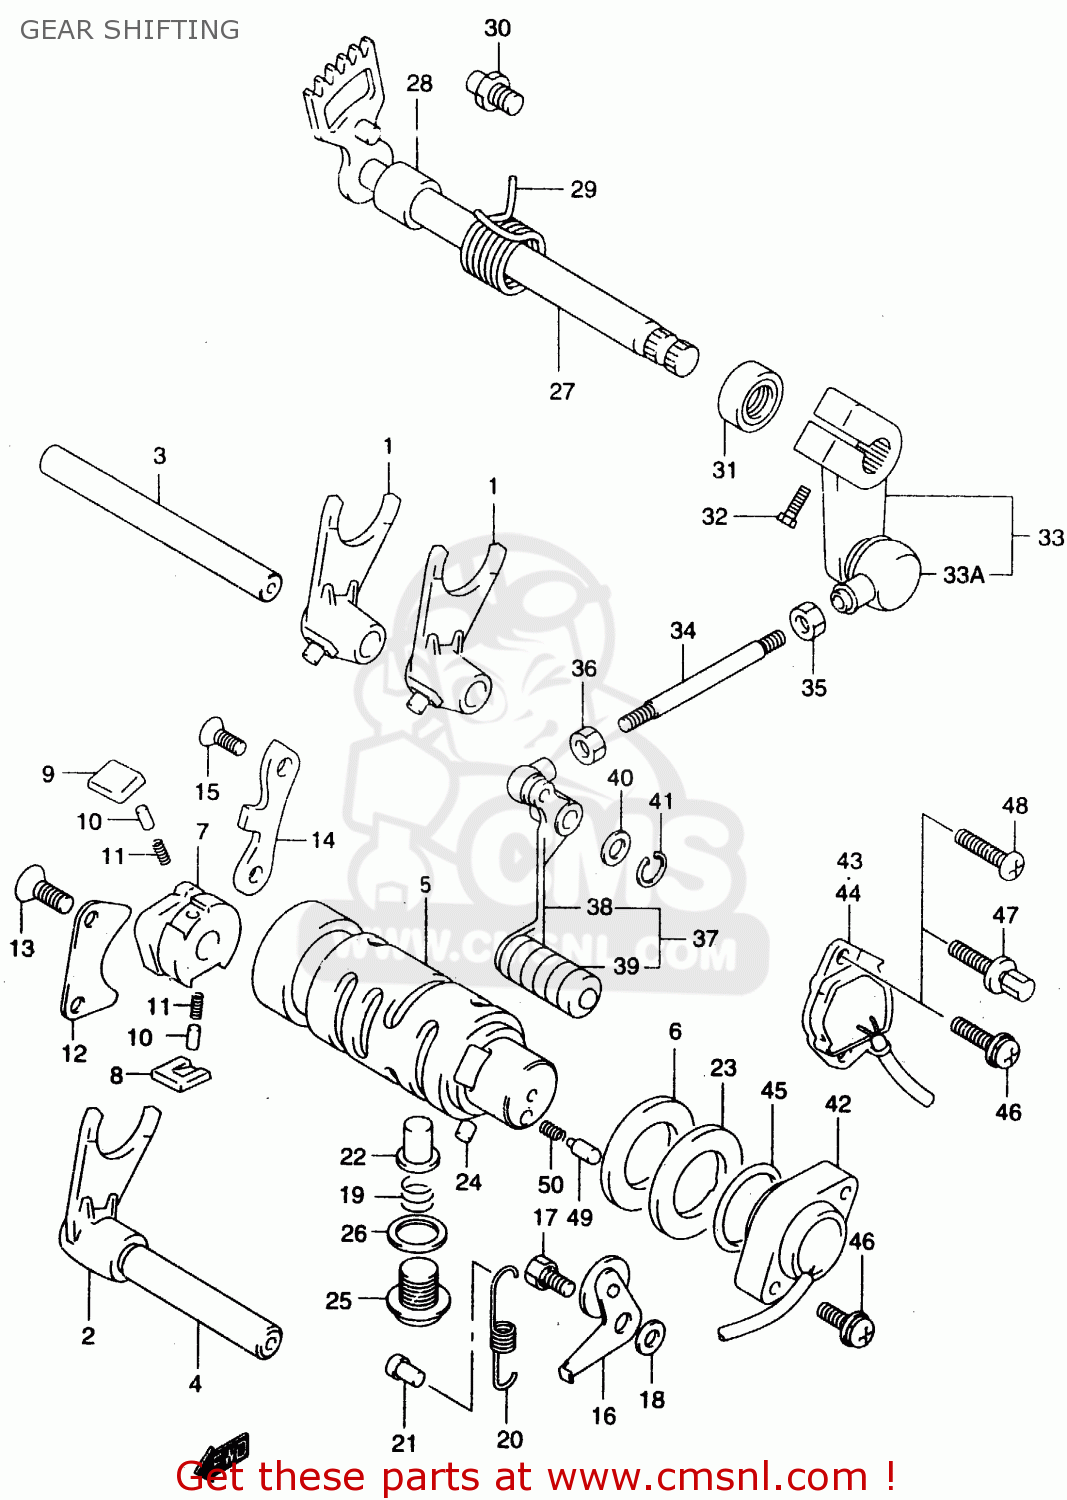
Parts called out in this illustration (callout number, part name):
1	FORK,GEAR SHIFT NO.2
2	FORK,GEAR SHIFT NO.3
3	SHAFT,GEAR SHIFT FORK(L:109)
4	SHAFT,GEAR SHIFT FORK
5	CAM,GEAR SHIFT
6	SHIM(25X40X1)
7	GEAR,GEAR SHIFT CAM DRIVEN
8	PAWL,GEAR SHIFT NO.1
9	PAWL,GEAR SHIFT NO.2
10	PIN(5X8)
11	SPRING
12	LIFTER,GEAR SHIFT POLE
13	SCREW
14	GUIDE,GEAR SHIFT CAM
15	SCREW
16	STOPPER,GEAR SHIFT CAM
17	BOLT(6X14.6)
18	WASHER
19	SPRING
20	SPRING
21	RIVET
22	STOPPER,GEAR SHIFT CAM NO.2
23	PLATE,GEAR SHIFT CAM STOPPER
24	PIN
25	PLUG(14X12)
26	GASKET(13.8X18.8X4.8) (NAS)
27	SHAFT,GEAR SHIFT
28	SPACER(12X20X15.3)
29	SPRING
30	STOPPER,GEAR SHIFT CAM
31	OIL SEAL
32	BOLT
33	ARM,GEAR SHIFT LINK
33A	COVER,DUST
34	ROD,GEAR SHIFT LINK
35	NUT
36	NUT
37	LEVER ASSY,GEAR SHIFT
38	COVER,DUST
39	RUBBER,GEAR SHIFT PEDAL
40	WASHER(12.5X20X1)
41	CIRCLIP,12 MM
42	BASE ASSY,GEAR SHIFT TERMINAL
43	BASE ASSY,GEAR SHIFT TERMINAL
44	BASE ASSY,GEAR SHIFT TERMINAL
45	O-RING (D:2.4 ID:26.2)
46	SCREW
47	BOLT
48	SCREW 5X20
49	PIN(5X15.5)
50	SPRING
